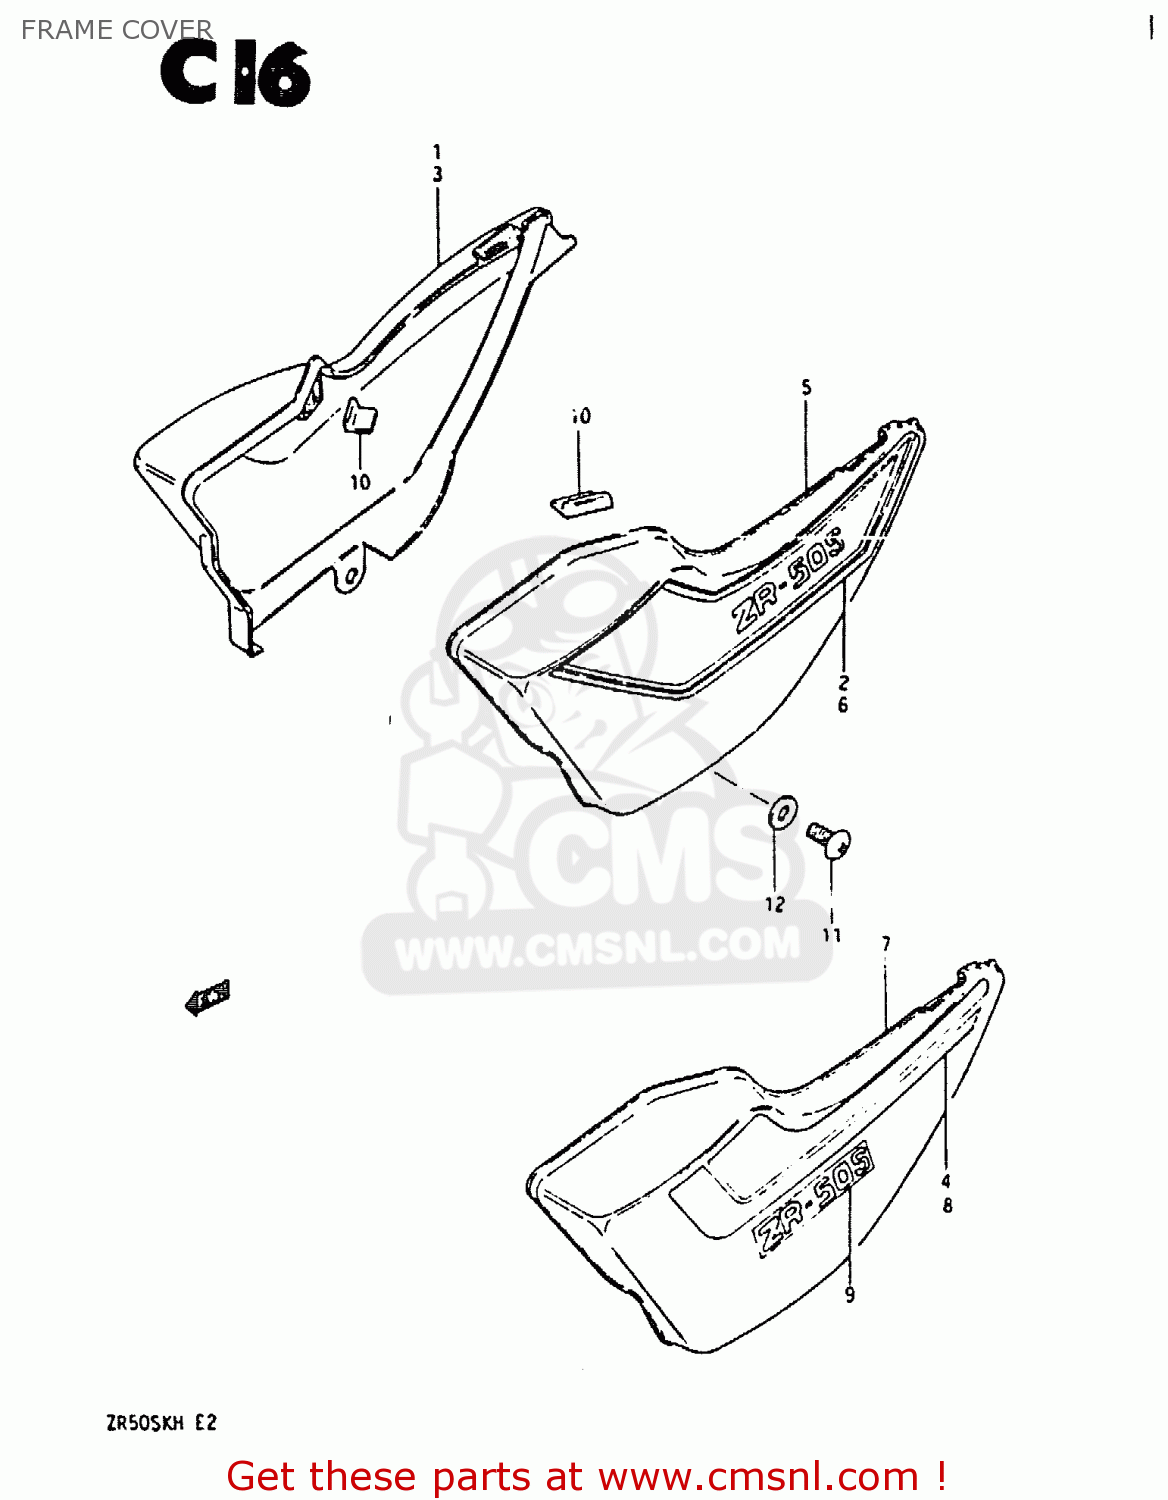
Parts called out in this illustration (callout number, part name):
1	COVER, FRAME RH (RED)
2	TAPE SET, FRAME COVER RH
3	COVER, FRAME RH (BLACK)
4	TAPE SET, FRAME COVER RH
5	COVER, FRAME LH (RED)
6	TAPE SET, FRAME COVER LH
7	COVER, FRAME LH (BLACK)
8	TAPE SET, FRAME COVER LH
9	EMBLEM
10	CUSHION,FRAME COVER
11	SCREW
12	WASHER
